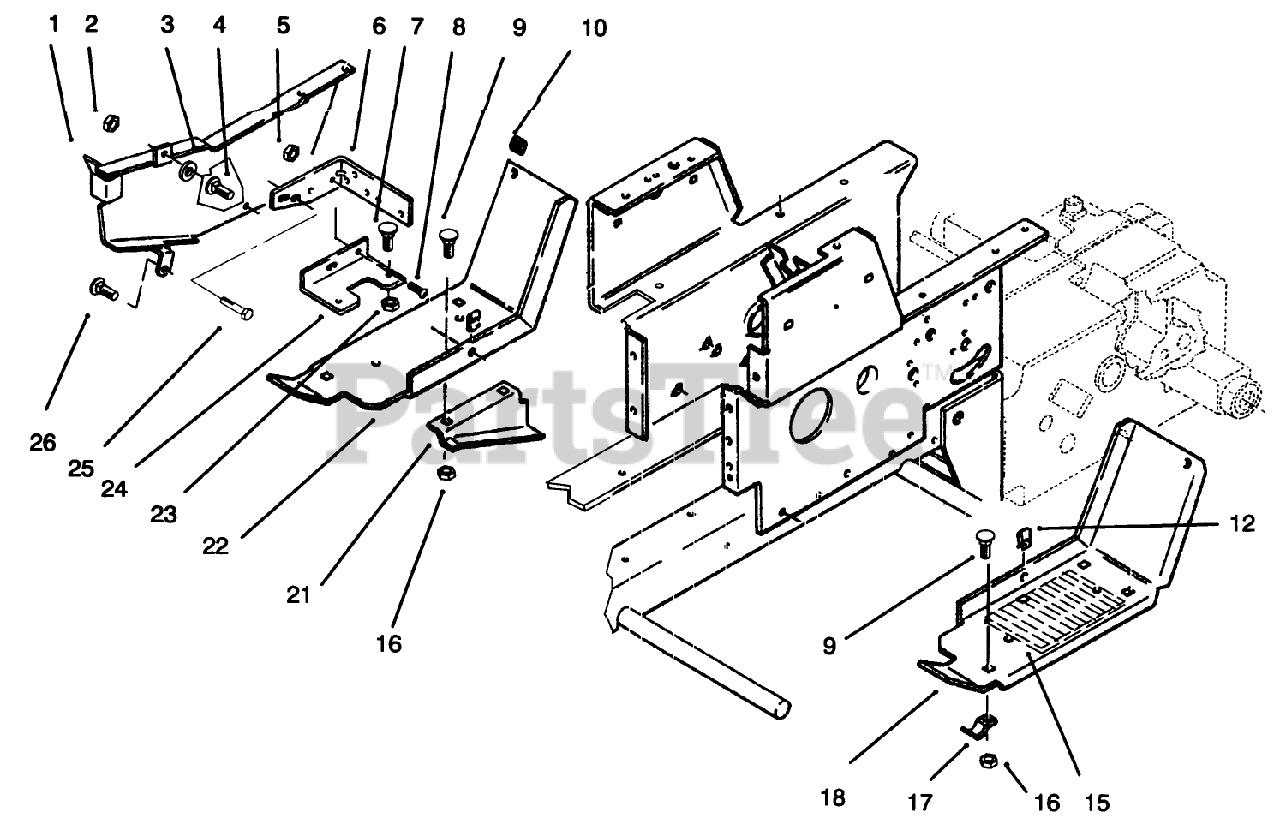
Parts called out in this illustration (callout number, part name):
2	NUT-LOCK, NI
4	SCREW-PPH
5	NUT-LOCK, NI
6	BRACKET-BELT*B
7	SCREW-PAN
8	SCREW-HH
9	BOLT-CARR
10	BUMPER
15	PAD FOOTREST
16	NUT-LOCK, NI
17	BRACKET
18	FOOTREST LH *R
24	BRKT-FUS HLDER*B
25	BOLT-CARR
